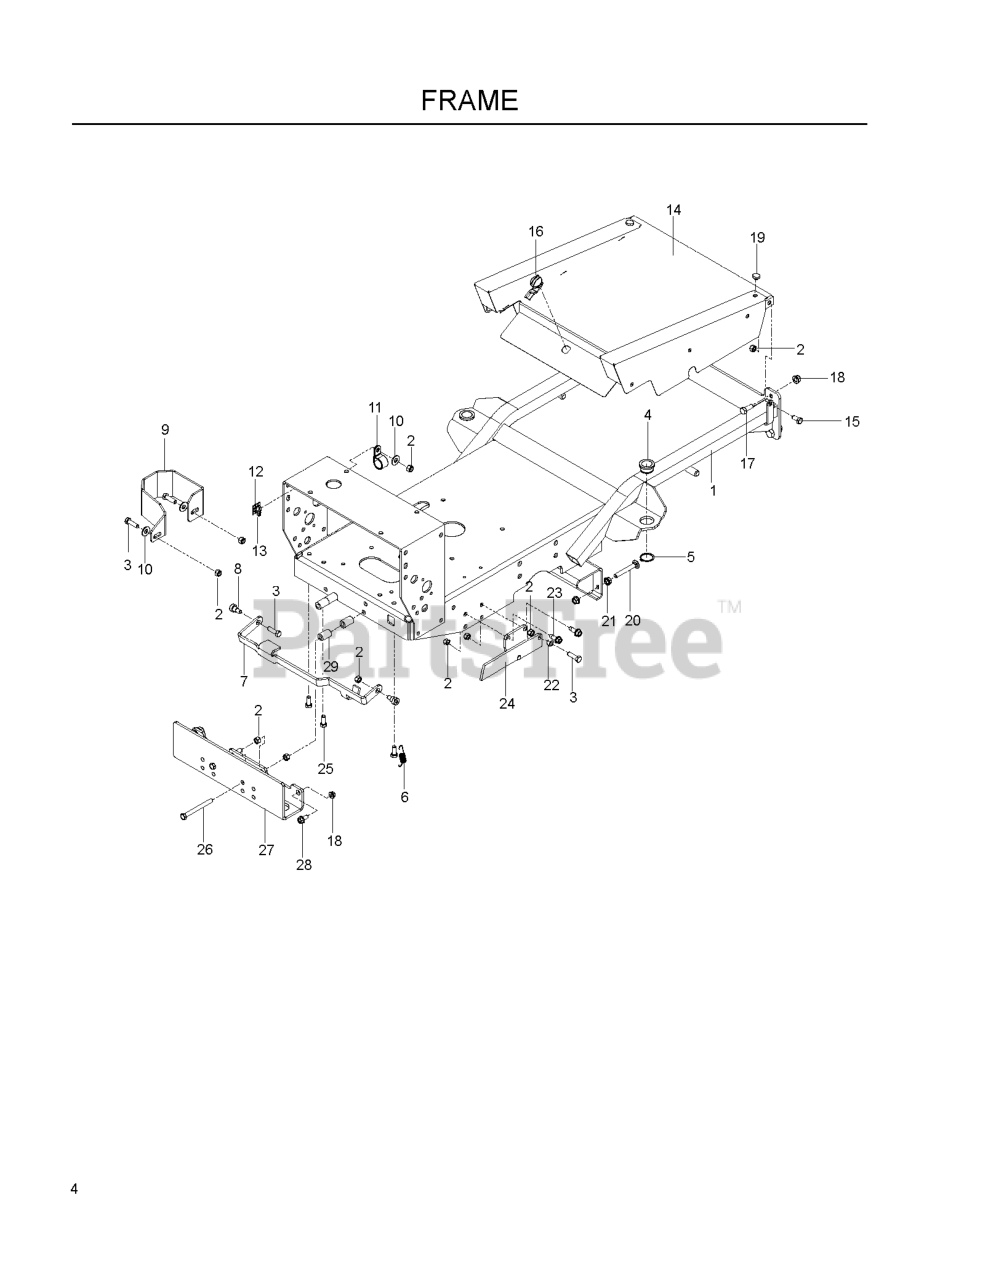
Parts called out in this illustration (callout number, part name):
1	CHASSIS WLDT ORANGE
2	NUT 3/8-16 NYLOC
3	HCS 3/8C X 1 1/4 GR5
4	BUSHING, BRONZE HOC
5	SNAP RING 1.25
7	BAR, THROWOUT OR
8	SB 3/8-16 X 3/8 SKT HD ZD
9	GUARD FILTER PAINTED
10	WASHER 3/8 FLAT
12	MOUNTING BLOCK CABLE TIE
13	TIE, PLASTIC
14	COVER, ASM, CENTER
15	SCREW 3/8C X 3/4 HEX CAP
16	LATCH, SHORT WING
17	HCS 1/2-13 X 1-1/4
18	NUT, 1/2-13 HEX FLG NYLOC ZD
19	GROMMET, BUMPER
20	RHSNB 3/8-16 x 2¾
21	NUT 3/8C WHIZ
22	NUT 3/8-16
23	BOLT 3/8-16 X 1.0
24	SUPPORT PLATE, P. BRAKE RH BLK
25	HCS 3/8-16 X 7/8 GR 5 ZD
26	HCS3/8-16.X
27	BUMPER, OR
